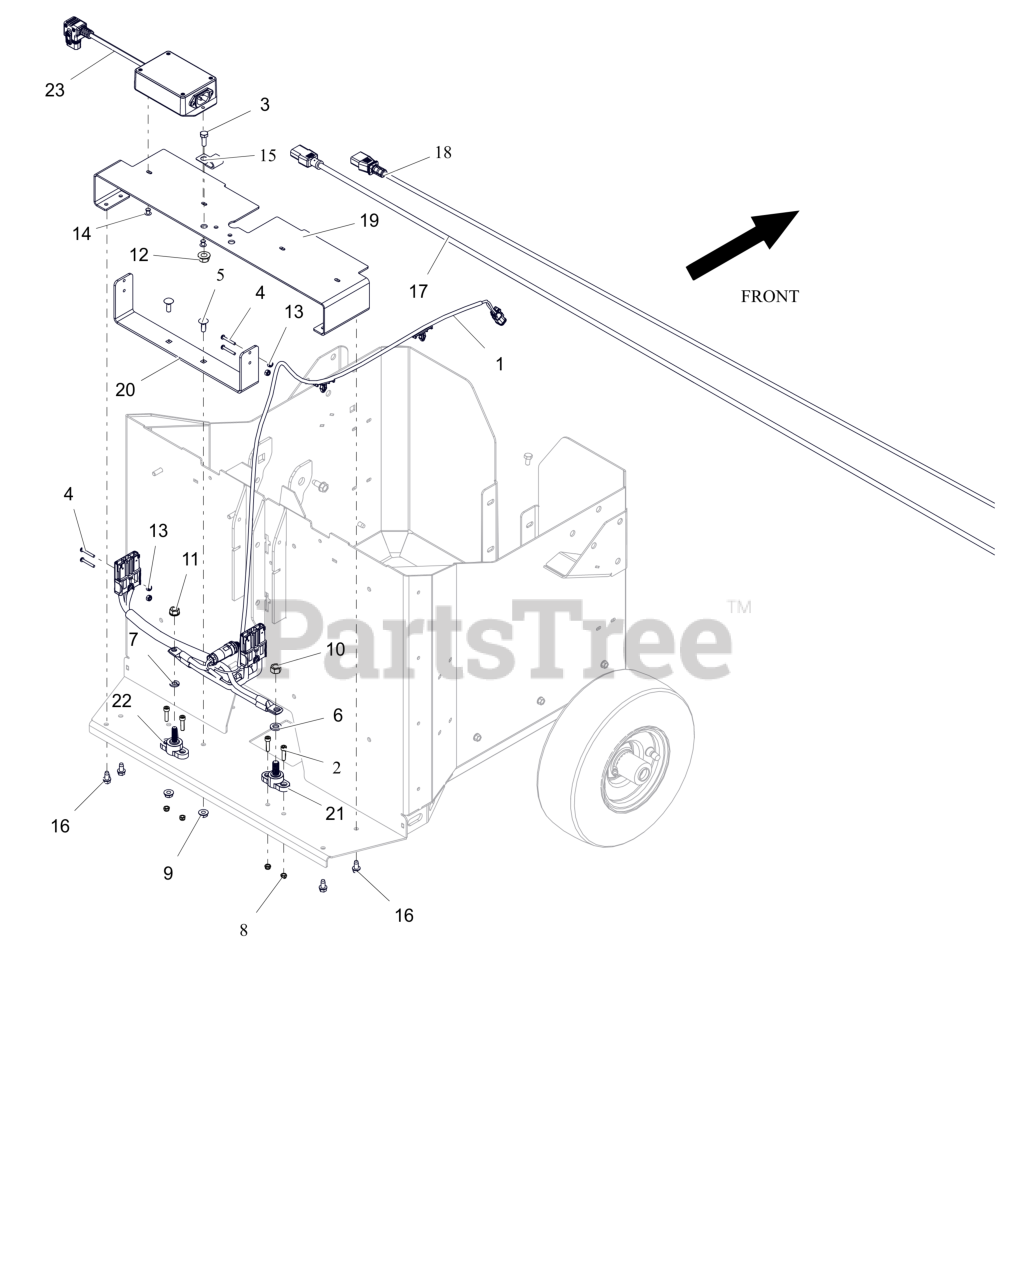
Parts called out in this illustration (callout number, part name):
1	HARNESS, OFFBOARD CHARGER
2	SCR, SKH M5-.8X20 12.9ZC120
3	BLT, HEX .25-20X.75 G5 ZCC
4	SCR, PH PAN HD #6-32X1.000 ZCC
5	BLT, RHSN .25-20X.750 G5 ZCC
6	WSHR,LK-REG .375X.094 ZCC
7	WSHR,LK-REG .312X.078 ZCC
8	NUT,NYL M5-.8 G8.8 ZCC
9	NUT-SPNLK-FLG .25-20 ZC120
10	NUT-LK-CTR .38-16 ZC120
11	NUT,LK-CTR-FLG .31-18 GF ZCC
12	NUT-LK-CTR-FLG .375-16 GF ZCC
13	@NUT-LK-NYL 6-32 W/INSRT YWZC
14	RVT-POP .187x.250 (#64) ZCC
16	SCR-TAP .25-20X.50 HWH ZCC
17	CORD, POWER US 120V AC
18	CORD, POWER US 220V AC
19	PLATE, GROUND SEPARATION (BLACK)
20	PLATE, CHARGER PLUG MNT (BLACK)
21	STUD, POSITIVE POWER
22	STUD, NEGATIVE POWER
23	FILTER ,EMI, 120/250V,50-60HZ
